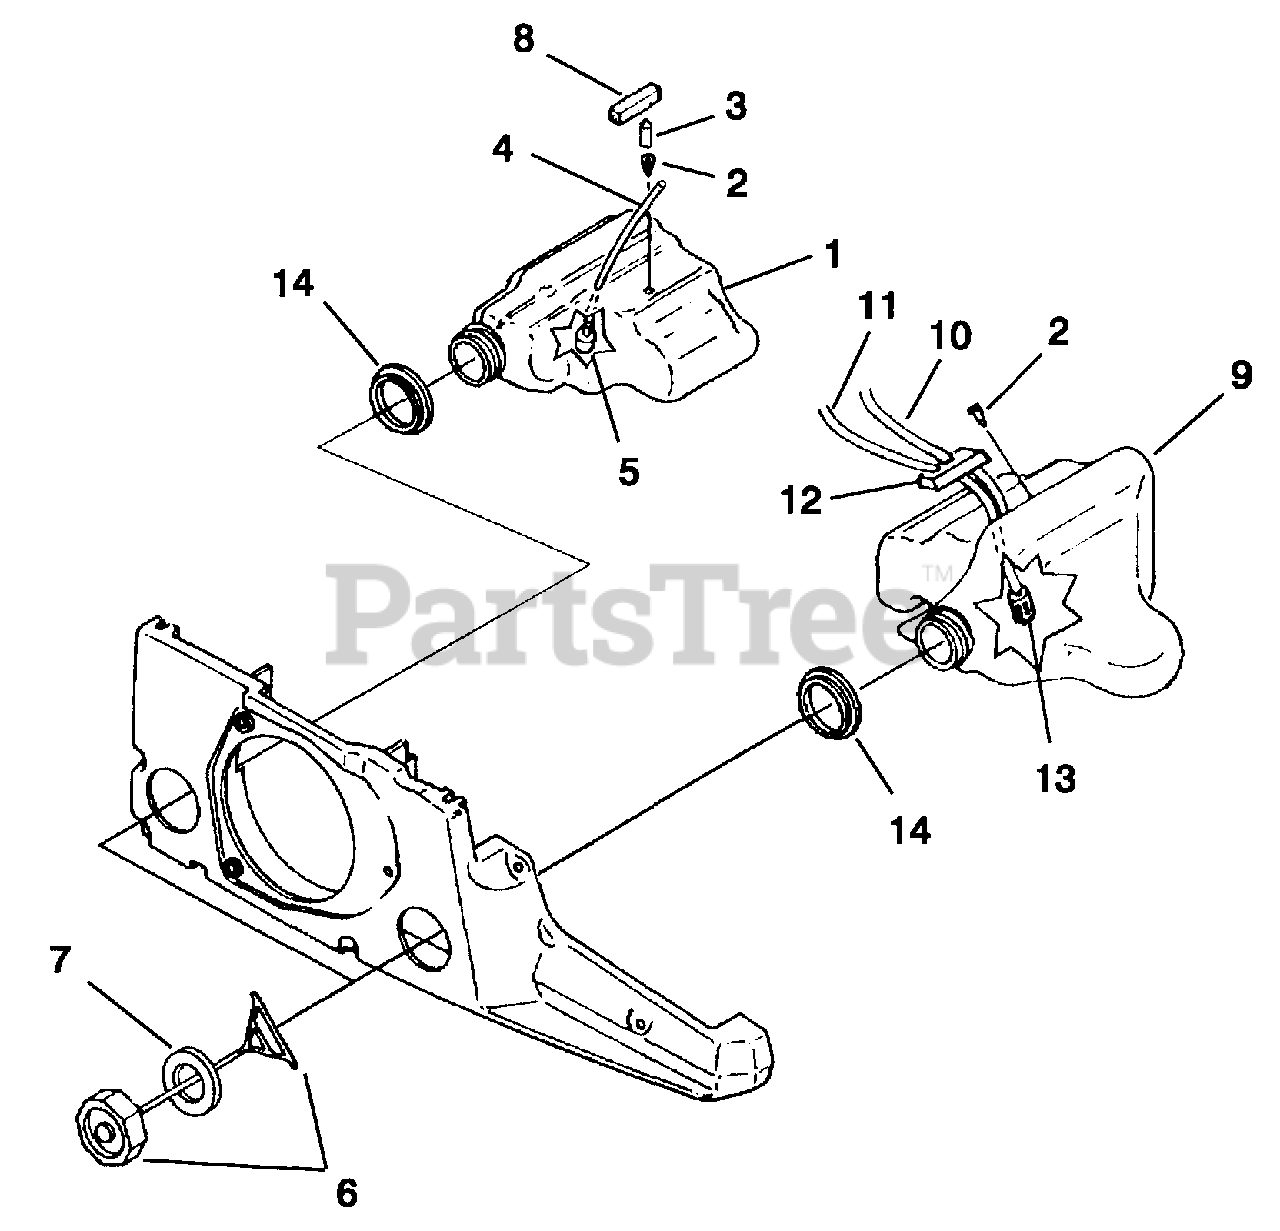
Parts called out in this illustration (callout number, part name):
1	OIL TANK ASSY
2	VALVE-Check
2	VALVE- Check
3	PIN-Spirol
4	TUBING- Rubber (7 1/4")
5	FILTER- Oil
6	CAP- Tank (w/Retainer)
7	GASKET Fuel Cap
8	FILTER- Oil Tank Valve
9	FUEL TANK ASSY
10	TUBING-Rubber (5 1/4")
11	TUBING- Rubber (9")
12	FILTER- Foam
13	FILTER- Fuel
14	SAWDUST SEAL
